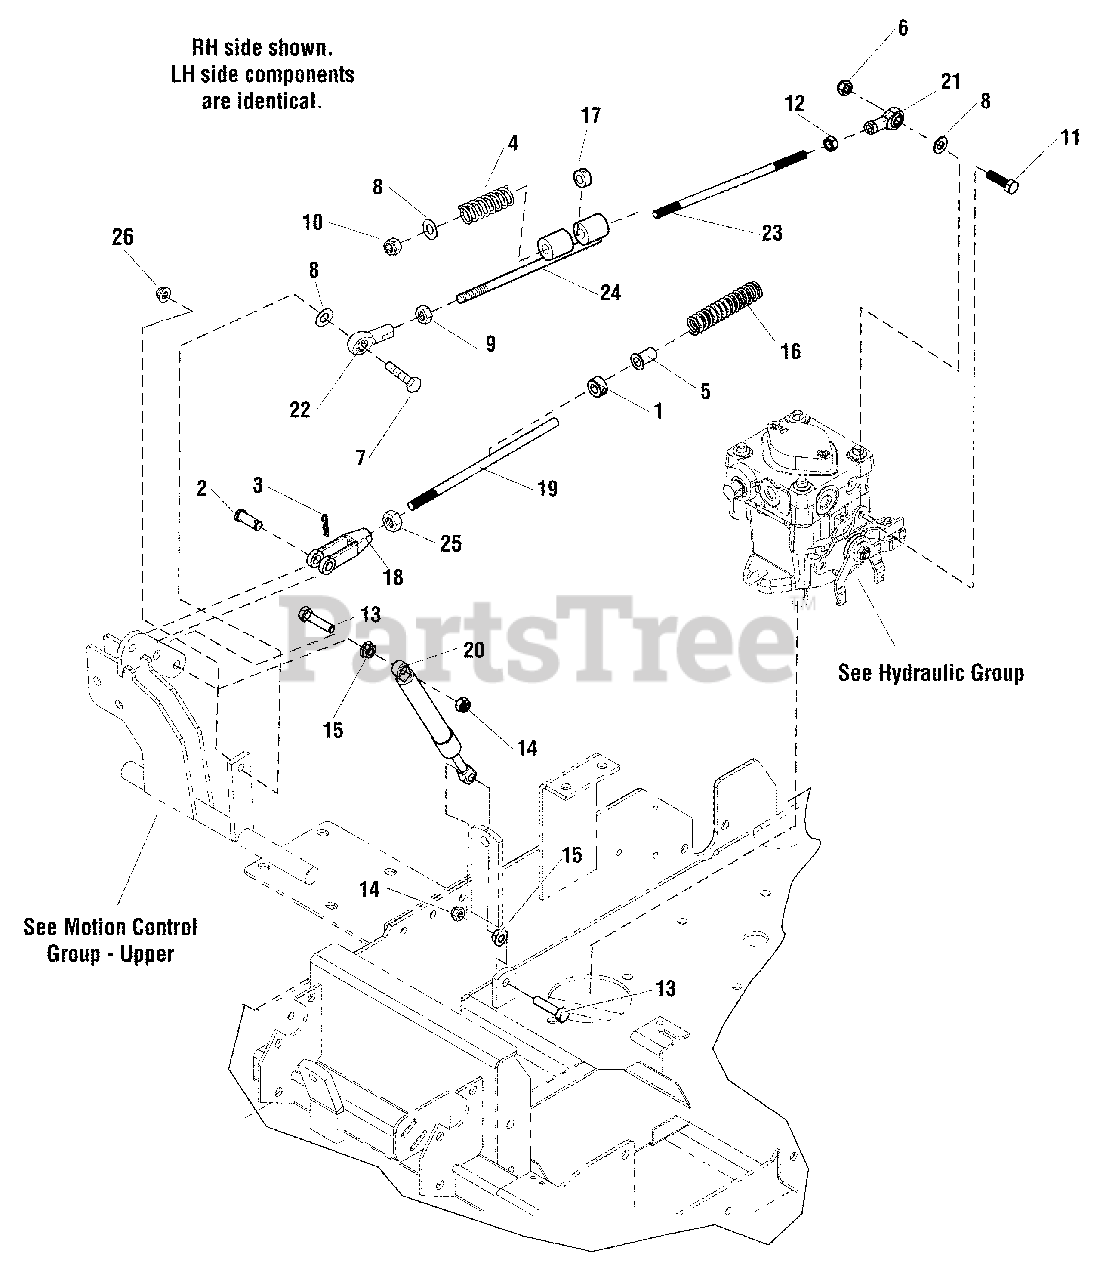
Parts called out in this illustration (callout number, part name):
1	COLLAR, 3/8" SET
2	PIN, CLEVIS, 3/8" X 1-1/8"
3	PIN, HAIR, .0585" X 1-1/8"
4	SPRING, CONTROL ROD
5	BUSHING, NYLON
6	NUT, 5/16-18 HEX NYLON LOCK
7	BOLT, 5/16-18 X 1-1/4" GD5 YZ
8	WASHER, 5/16" SAE
9	NUT, 5/16-24 HEX
10	NUT, 5/16-24 HEX NYLON LOCK
11	BOLT, 5/16-18 X 1" GD5 YZ
12	NUT, 5/16-24 HEX, LH
13	BOLT, M8-1.25 X 35MM, GD8.8
14	NUT, M8-1.25 NYLON LOCK, CZ
15	NUT, M8-1.25 SERR. FLANGE, CZ
16	SPRING, REVERSE RETURN
17	COLLAR, 5/16" SET
18	CLEVIS 3/8-24, PLASTIC
19	ROD, NEUTRAL CONTROL, 8
20	DAMPENER
21	BALL JOINT 5/16-24 LH FEMALE STAMPED STL
22	BALL JOINT 5/16-24 RH FEMALE STAMPED STL
23	ROD, 5/16 X 8.38, LH-RH, CZ
24	WELD, CONTROL ROD SLIDING
25	NUT, 3/8-24 HEX
26	NUT, 5/16-18 HEX NYLOCK FLANGE
